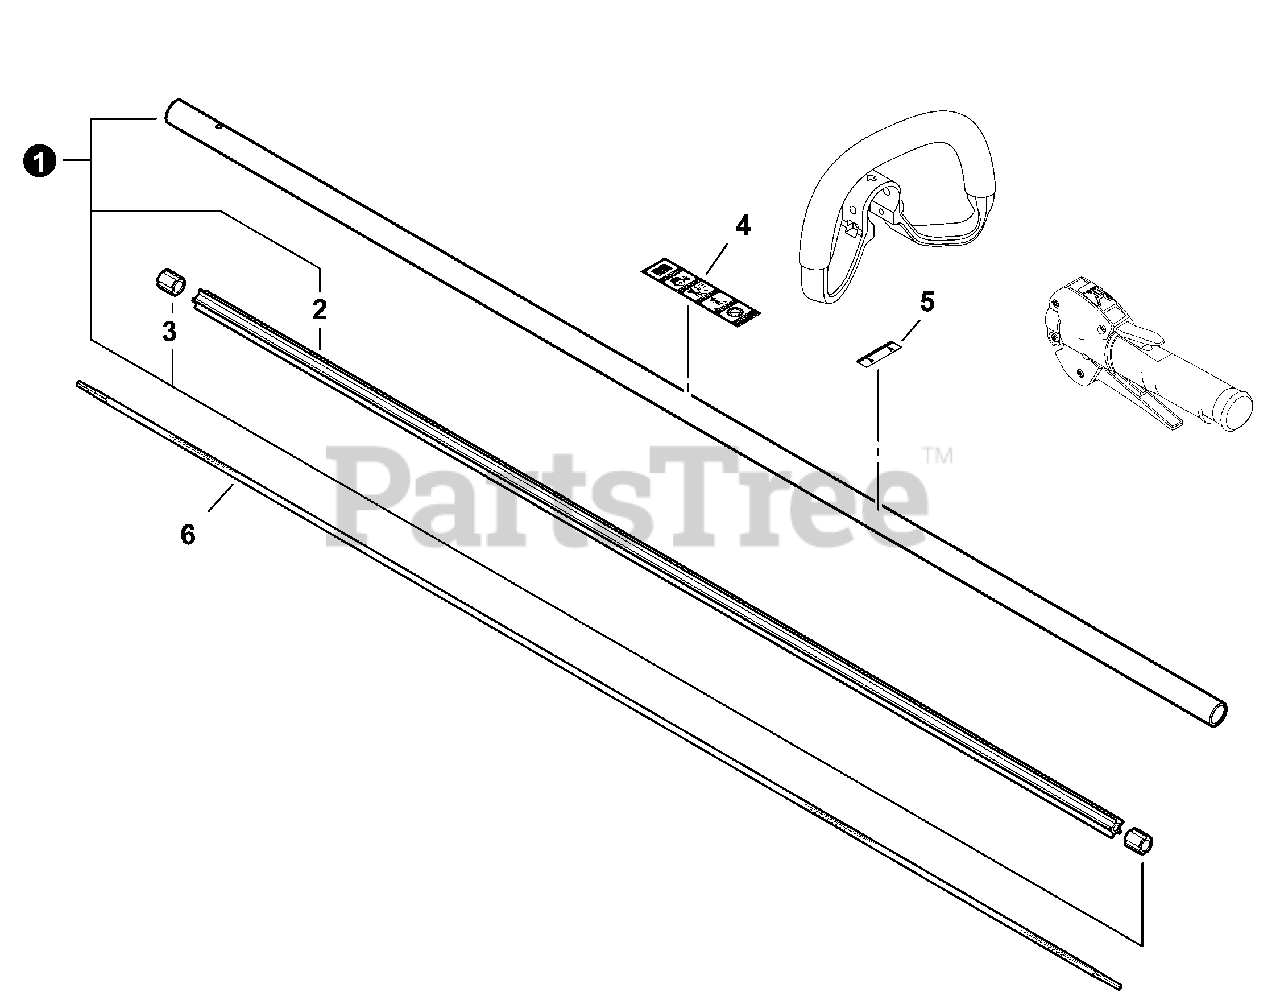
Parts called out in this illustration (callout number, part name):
1	MAIN PIPE ASSY
2	LINER, FLEXIBLE 21.6×1420
4	LABEL, CAUTION
5	LABEL - ALIGNMENT
6	DRIVESHAFT - FLEXIBLE
